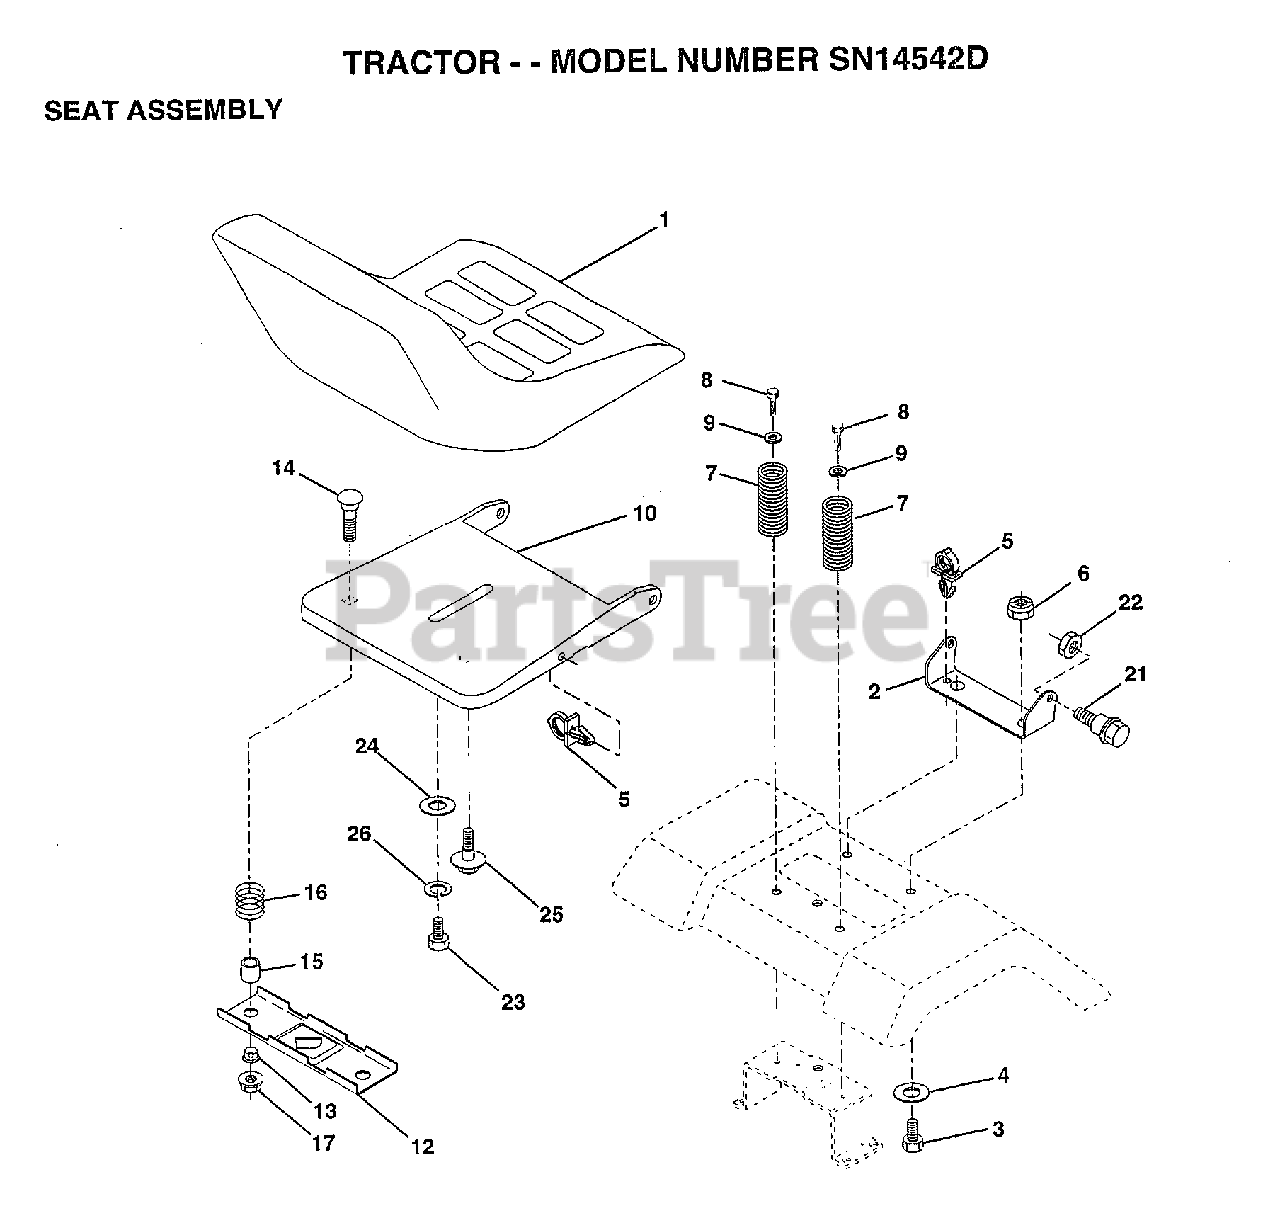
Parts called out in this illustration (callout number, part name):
2	BRACKET PVT SEAT
3	BOLT
4	WASHER PM
5	CLIP.PUSH-IN.HING
6	NUT
7	SPRING COMPRESSIO
8	SCREW GTV
9	WASHER
10	PAN-SEAT
12	BRKT SWITCH
13	BUSHING
14	BOLT-RD HD SQ NK
15	SPLIT SPACER
16	SPRING
21	"BOLT,SHOULDER"
22	NUT
23	BOLT
24	WASHER
25	"BOLT,SHOULDER"
26	LOCKWASHER
